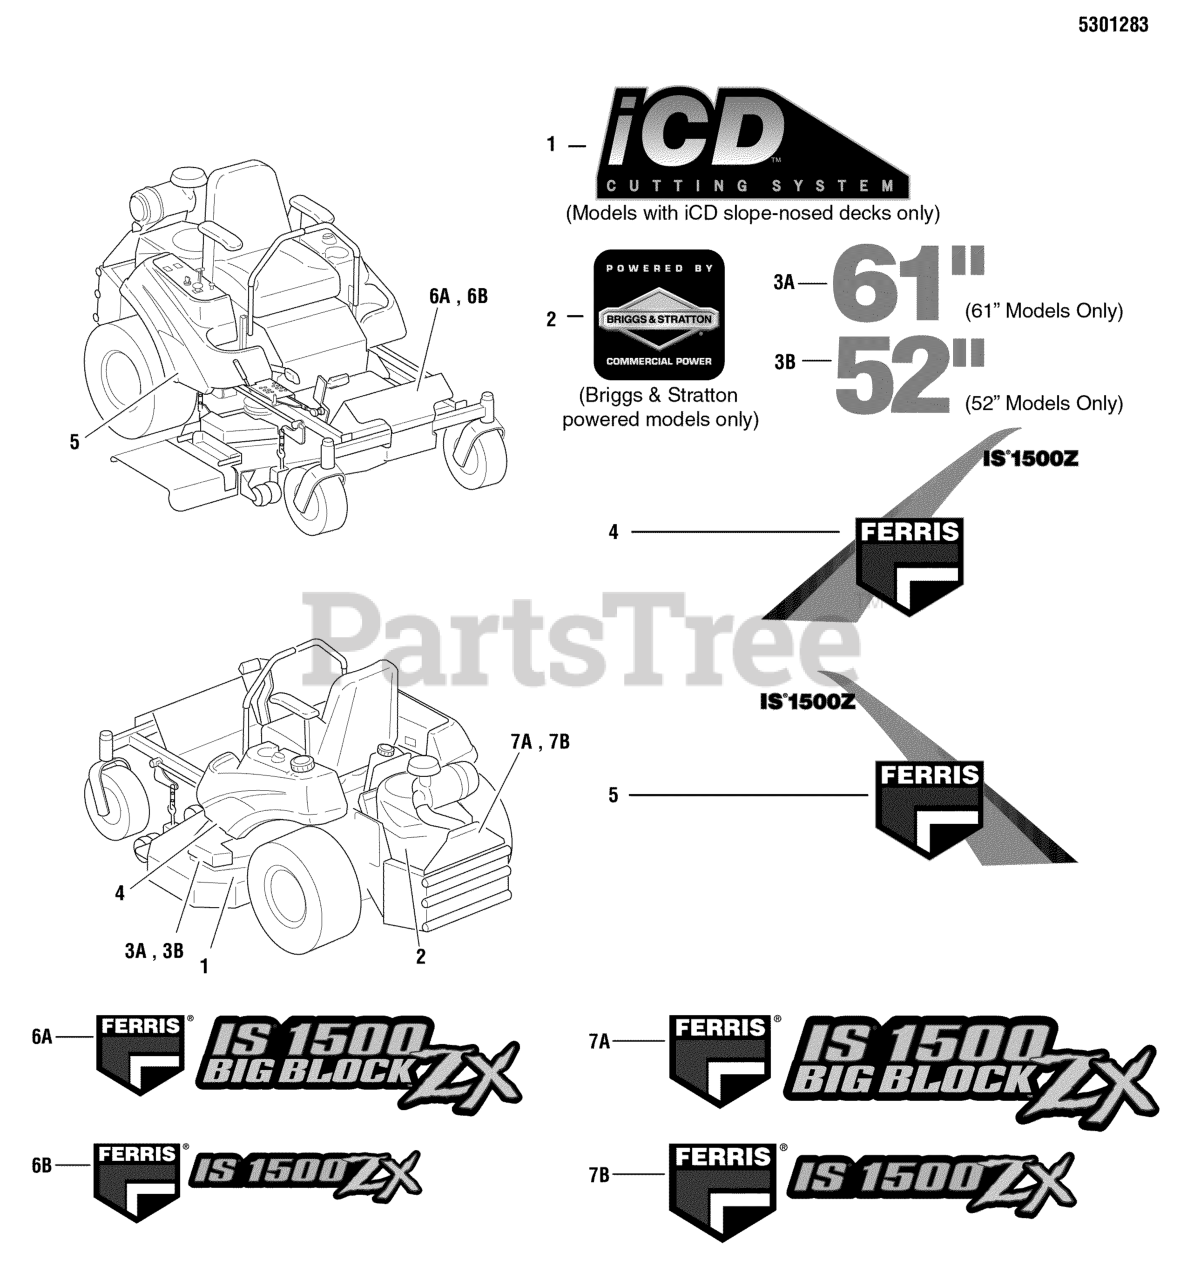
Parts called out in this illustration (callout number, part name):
1	DECAL, ICD CUTTING SYSTEM
4	DECAL, BADGE, LH - IS1500
5	DECAL, BADGE, RH - IS1500
